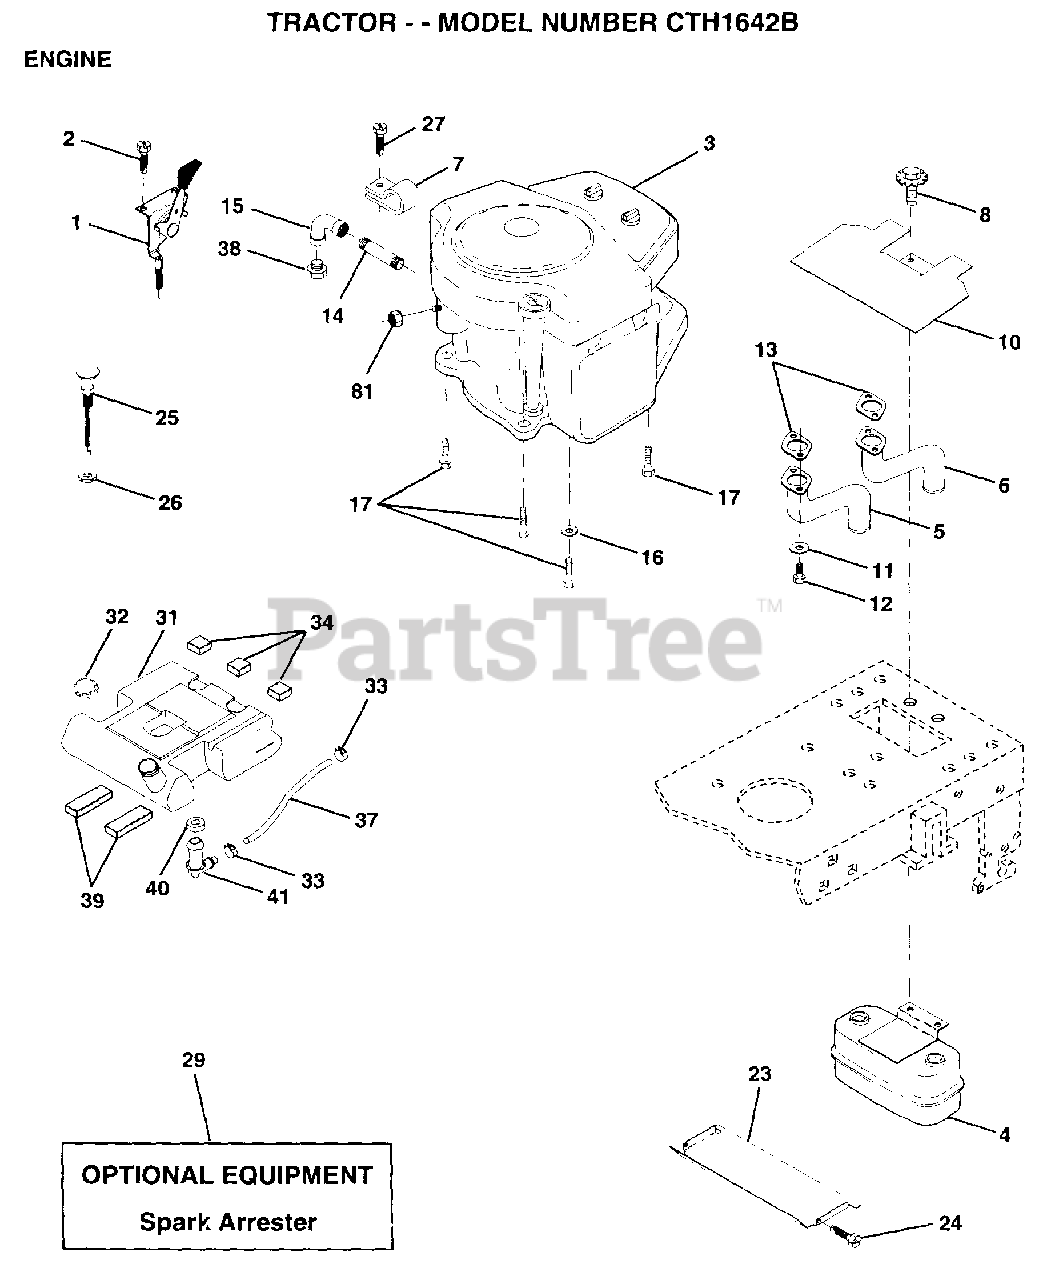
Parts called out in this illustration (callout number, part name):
2	SCREW LT
4	MUFFLER.TW.LOTONE
5	EXHAUST.B&S.18.LH
6	EXHAUST.B&S.18.RH
7	CLAMP.TUBE.DBL.EN
8	BOLT.5/16-18.UNC
10	SHIELD.HEAT.
11	LOCKWASHER
13	GASKET MUFFLER
14	PIPE NIPPLE LT
15	ELBOW
16	LOCKWASHER
17	SCREW LT
23	HEAT SHIELD
24	SCREW
25	"CONTROL.CHOKE.51"""
26	"NUT,KEPS 3/8-24IM"
27	SCREW.10-24X1/2
32	CAP ASM FUEL
33	HOSE CLAMP
34	PAD-SPACER LT
37	FUEL LINE T
39	PAD IDLER TI
40	BUSHING OUTLET T
41	STEM.TANK.FUEL
81	NUT
